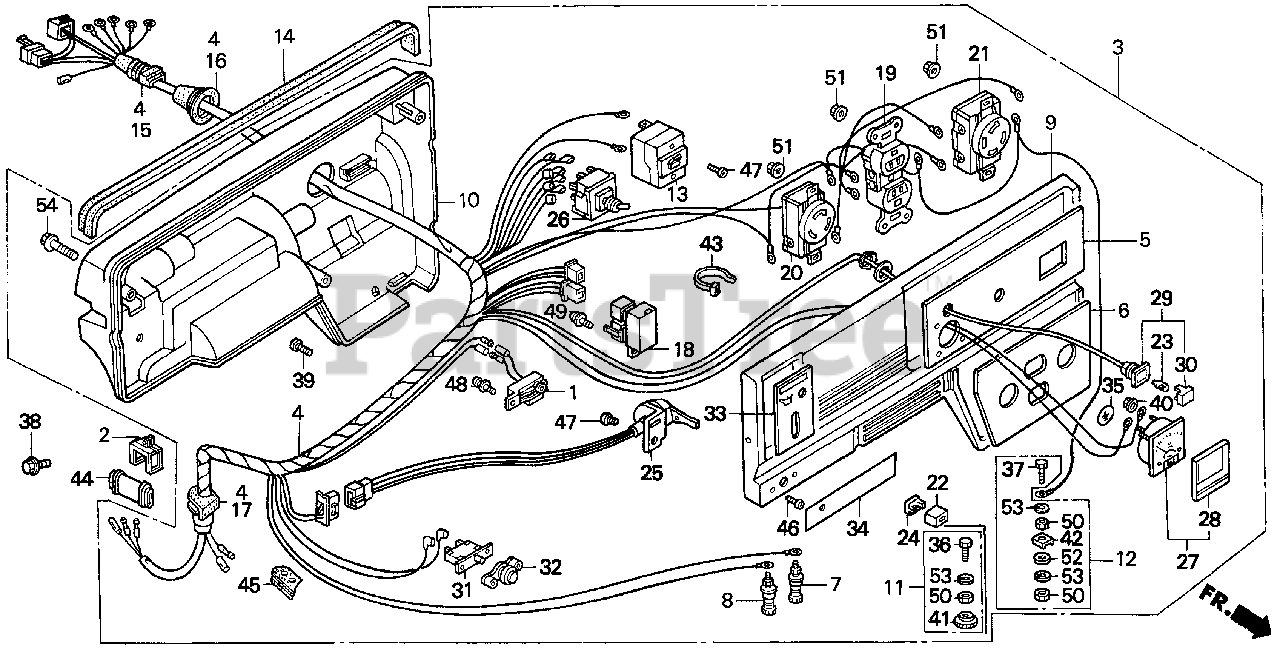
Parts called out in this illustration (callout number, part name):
1	ALERT UNIT, OIL (NOT AVAILABLE)
2	CLIP, WIRE
3	BOX ASSY., CONTROL *R8* (BRIGHT RED)
4	WIRE HARNESS ASSY.
4	WIRE HARNESS ASSY. (NOT AVAILABLE)
5	MARK, SWITCH PANEL (EMS-A)
6	MARK, A.C. OUT (NOT AVAILABLE)
7	TERMINAL, D.C. OUT (+)
8	TERMINAL, D.C. OUTPUT (-)
9	PANEL, CONTROL *R8* (BRIGHT RED)
9	PANEL, CONTROL *R8* (BRIGHT RED) (NOT AVAILABLE)
10	CASE, CONTROL *R280* (POWER RED)
11	TERMINAL SET, GROUND
12	TERMINAL SET, GROUND
13	BREAKER, CIRCUIT (13A)
14	RUBBER, CONTROL
15	GROMMET, A.C. WIRE
16	GROMMET, MAIN WIRE
17	GROMMET, SWITCH WIRE
18	DIODE ASSY.
19	RECEPTACLE (20A/125V) (MATSUSHITA)
20	RECEPTACLE (3-PRONG) (30A/125V)
21	RECEPTACLE (20A-125/250V) (MATSUSHITA) (NOT AVAILABLE)
22	KNOB, PETCOCK LEVER
23	BULB, WEDGE BASE (12V/2W) Use from Frame SN 1001725.
24	BUSH, CONTROL KNOB
25	SWITCH ASSY., ENGINE STOP
26	SWITCH ASSY., VOLT CHANGE
27	METER ASSY., VOLT (300V)
28	LENS, METER
29	SOCKET ASSY., LAMP (GREEN) Use from Frame SN 1001725.
30	LENS (GREEN) Use from Frame SN 1001725.
31	PROTECTOR, CIRCUIT (D.C.)
32	LENS ASSY., PROTECTOR
33	MARK, ENGINE SWITCH
34	MARK, D.C. OUT
35	MARK, GROUND
36	BOLT, HEX. (6X22)
37	BOLT, HEX. (6X28)
38	BOLT, FLANGE (6X12) (CT200)
39	SCREW, GLOVE BOX
40	NUT, FLANGE (3MM) Use from Frame SN 1001725.
41	NUT, SPECIAL (6MM)
42	RETAINER (6MM)
43	TIE, CABLE (NATURAL 225X5.0)
44	TUBE, CORD
45	GROMMET, TUBE
46	SCREW, PAN (3X12)
47	SCREW, PAN (4X6)
48	SCREW-WASHER (4X10)
49	SCREW-WASHER (4X12) Use up to Engine SN 2056819.
50	NUT, HEX. (6MM)
51	NUT, FLANGE (4MM)
52	WASHER, PLAIN (6MM)
53	WASHER, SPRING (6MM)
54	BOLT, FLANGE (6X40)
